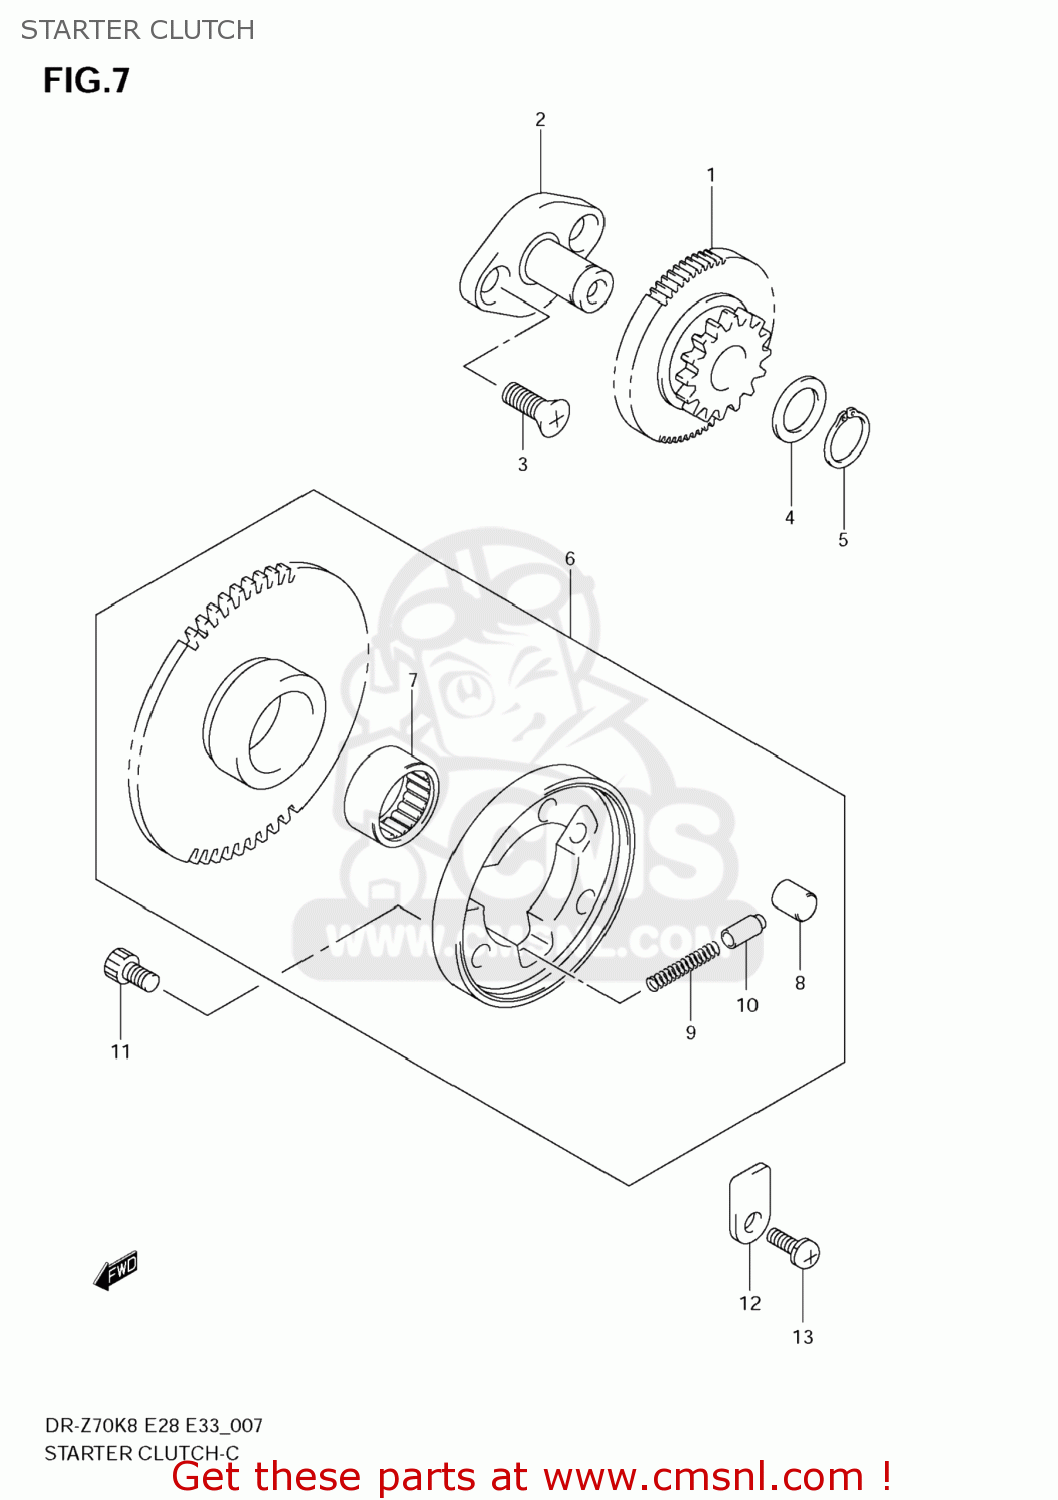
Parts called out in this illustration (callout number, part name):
1	GEAR,STARTER IDLE(NT:68/16)
2	SHAFT,STARTER IDLE GEAR
3	SCREW
4	WASHER(13X20X1)
5	CIRCLIP
6	CLUTCH SET,STA
7	BEARING(17X25X15)
8	PIN(9X10)
9	SPRING
10	PIECE,STARTER CLUTCH PUSH
11	BOLT(6X12)
12	PLATE,STARTER CLUTCH GEAR
13	SCREW
